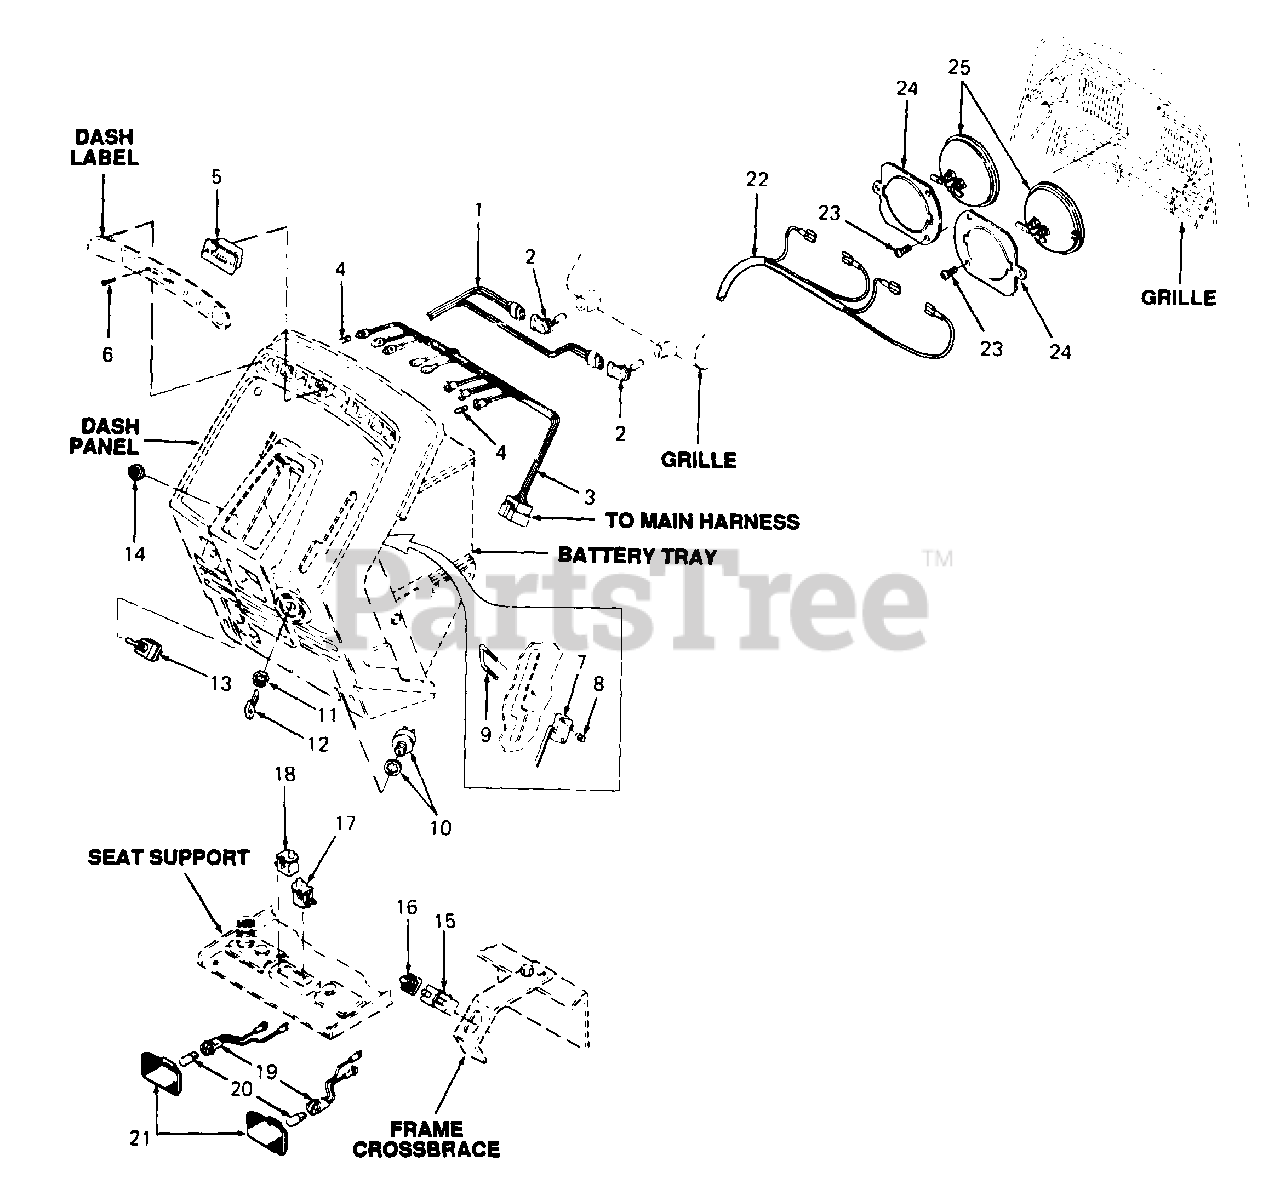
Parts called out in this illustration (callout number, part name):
1	Harness, Main Wire
2	Bulb, Head Lamp
3	Harness, Indicator Wire
4	Bulb, Indicator
5	Hour Meter
6	Screw, Truss Hd Tapp, #6 x .62 Lg
7	Switch, Reverse
8	Nut, Hex Insert Lock, #4-40
9	Screw, Switch
10	Switch, Ignition
11	Nut, Ignition Switch
12	Key, Ignition
13	Switch, PTO
14	Nut, Hex, 1/2-27 x .100 Thk
15	Switch, Interlock
16	Boot, Switch
17	Switch, Snap Mount - Normally Closed (Grey)
18	Switch, Snap Mount - Normally Open (Black)
19	Cable Assy, Tail Light
20	Bulb, Tail Light
21	Lens Assy, Tail Light
22	Harness, Main Wire
23	Screw, Pan Hd Tapp, #12 x .50 Lg
25	Headlamp, Sealed Beam
